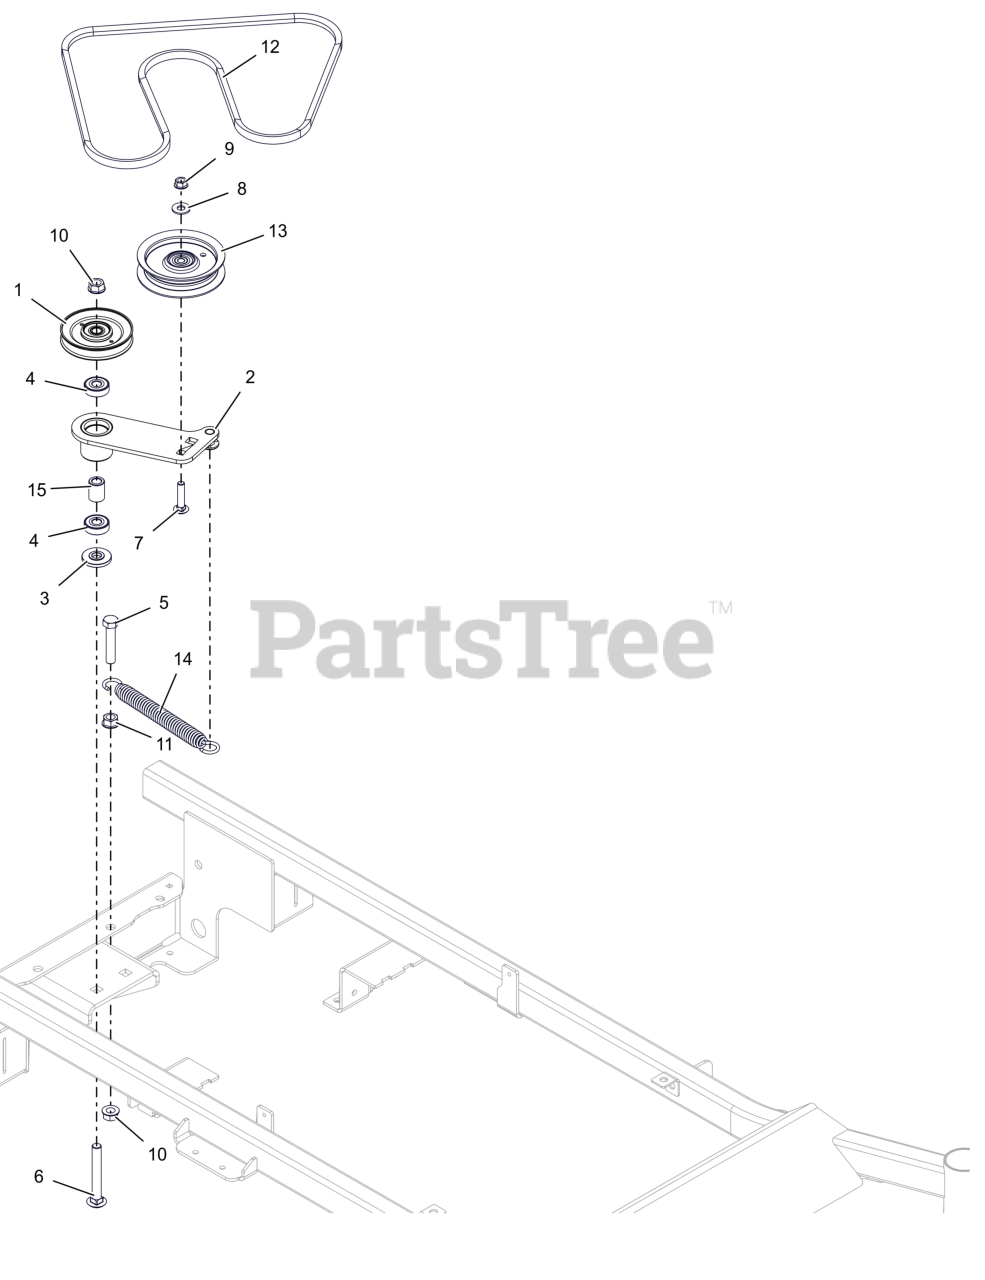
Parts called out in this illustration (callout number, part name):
1	SHEAVE, IDLER -V .50 X 4.000
2	WLDMT, 48-52" IDLER ARM
3	SPACER, IDLER ARM
4	BRG-BALL .500X1.38X.437
5	BLT, HEX .50-13X2.50 G5 ZCC
6	BLT,RHSN .500-13 X 3.75 G5 ZCC
7	BLT, RHSN .38-16X1.75 G5 ZCC
8	WSHR,FLT .438X1.00X.083 ZCC
9	NUT-LK-CTR-FLG .375-16 GF ZCC
10	NUT-LK-CTR-FLG .500-13 GG ZCC
11	NUT, SPNLK-FLG .50-13 G5 ZCC
12	V-BELT, HA SECTION
13	IDLER, FLAT - 4.06" X .75"
14	SPRING- EXTENSION
15	SPACER .510 X .867 X 1.1485
